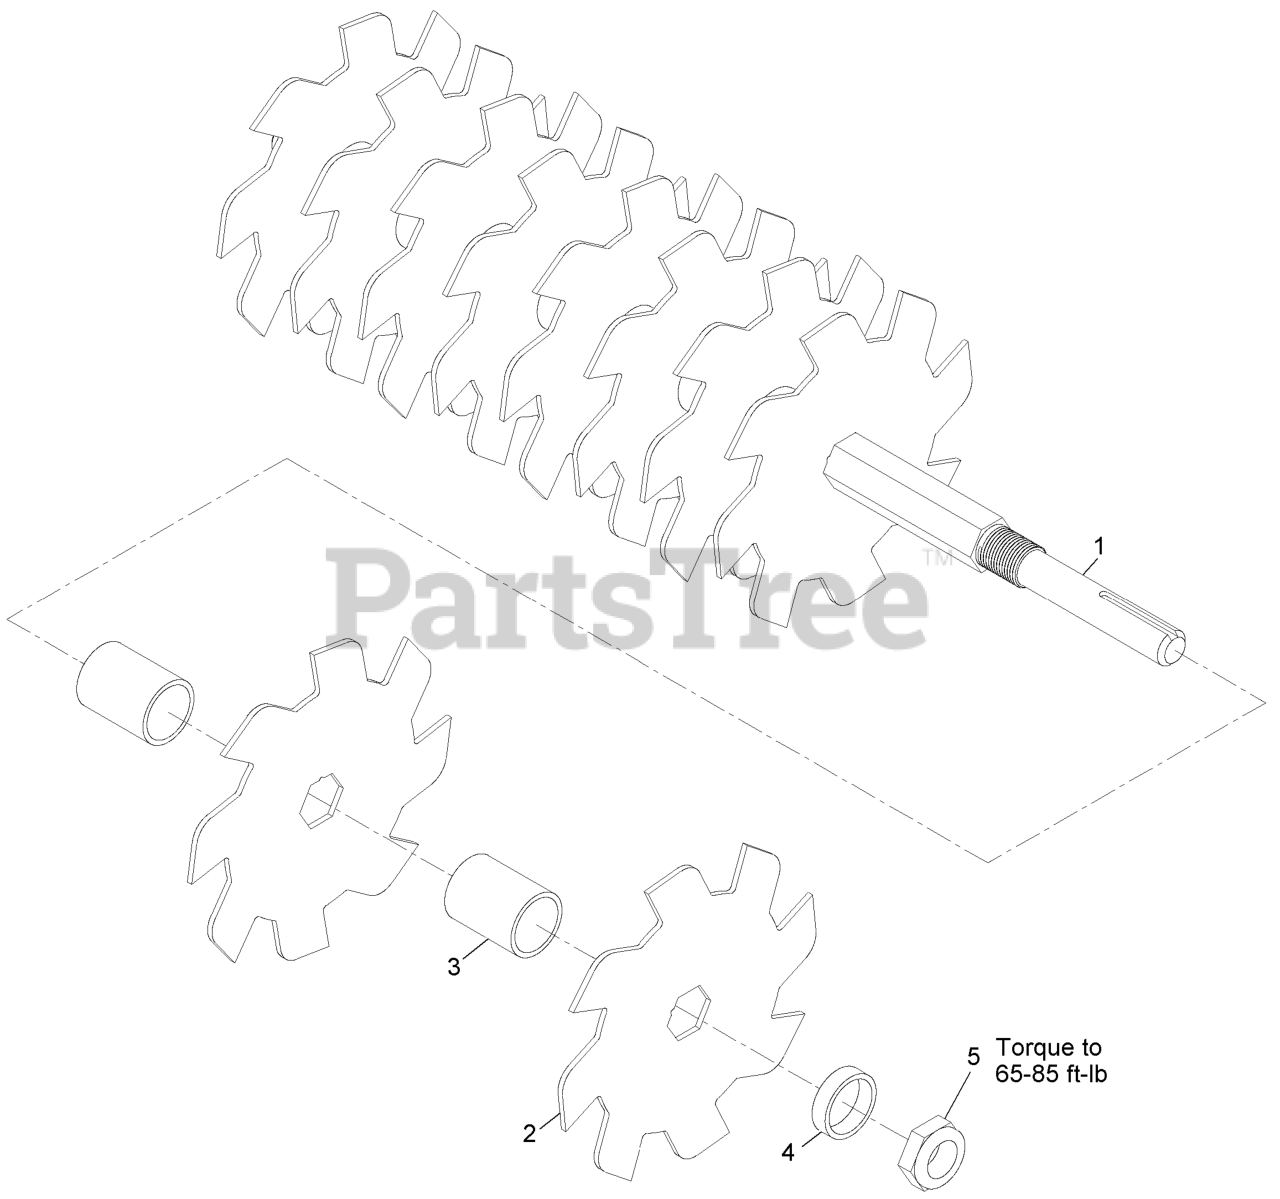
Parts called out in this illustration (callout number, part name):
1	SHAFT-SLICER
2	BLADE-CUTTING, SEEDER
3	SPACER-BLADE
5	NUT-LOCK, NI
